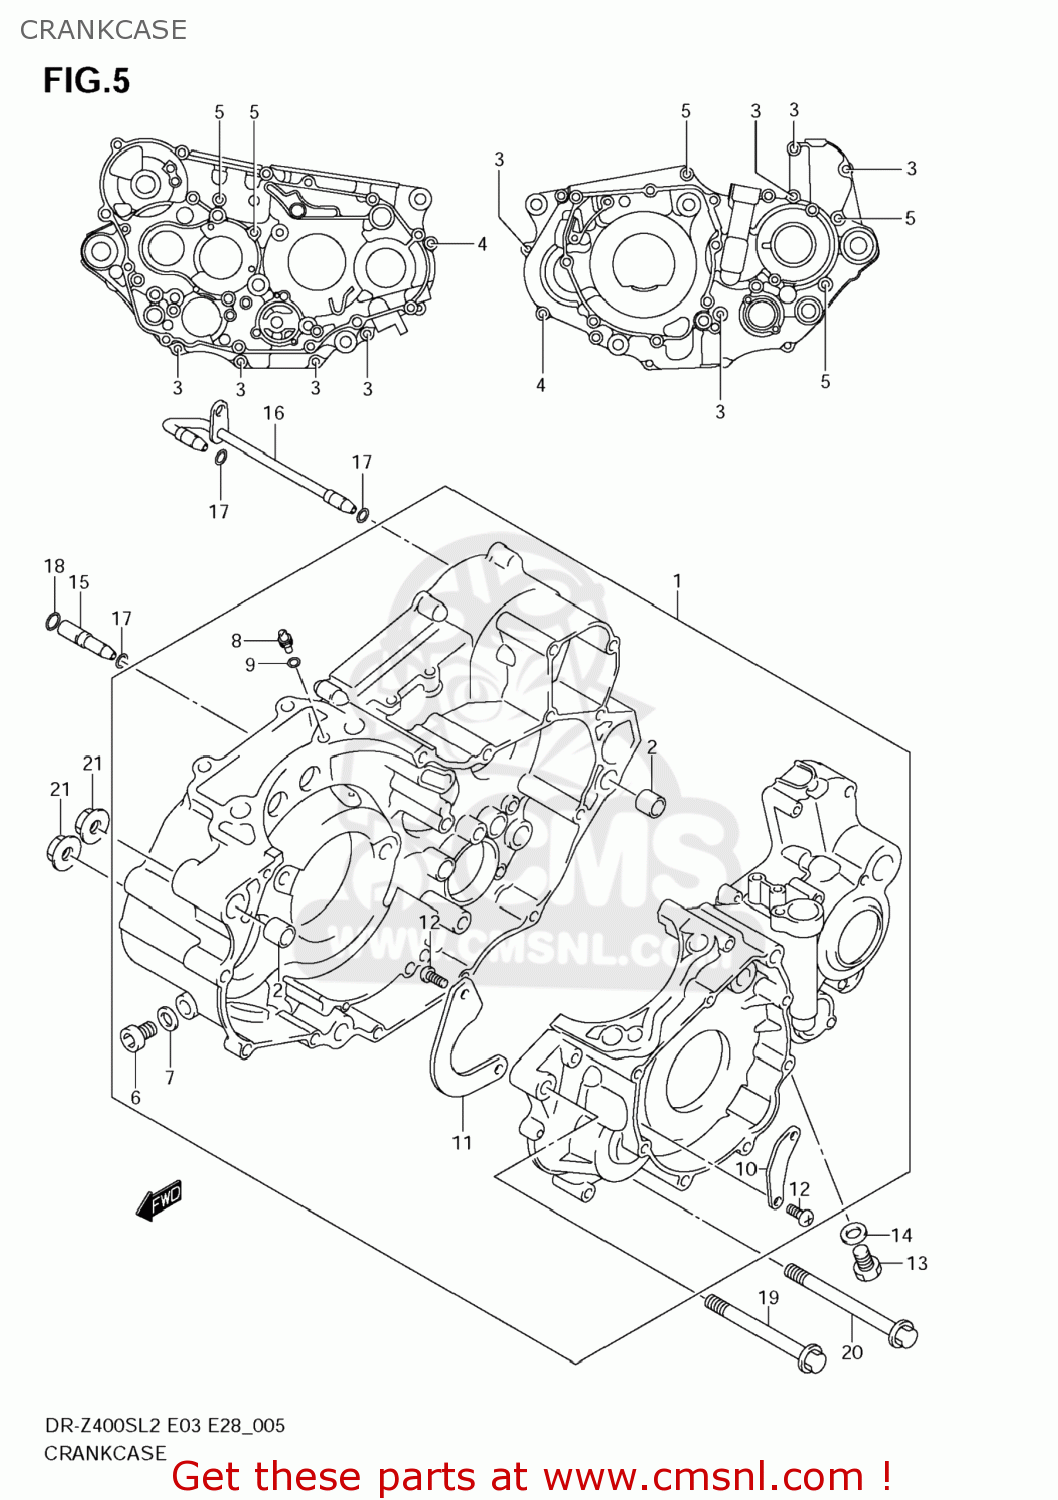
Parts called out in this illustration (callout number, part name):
1	CRANKCASE SET
2	PIN
3	BOLT
4	BOLT
5	BOLT
6	PLUG(10X10)
7	GASKET(10X14X3.6) (NAS)
8	JET(8)
9	O RING(D:1.2,ID:4)
10	SEPARATOR,CRANKCASE OIL NO.1
11	SEPARATOR,CRANKCASE OIL NO.2
12	SCREW(6X12)
13	PLUG(12X20)
14	GASKET(12.1X16.2X3.7) (NAS)
15	PIPE,OIL INNER NO.1
16	PIPE,T/M OIL INNER NO.2
17	O RING(D:1.9,ID:4.8)
18	O RING(D:1.9,ID:6.8)
19	BOLT(10X100)
20	BOLT(10X115)
21	NUT
